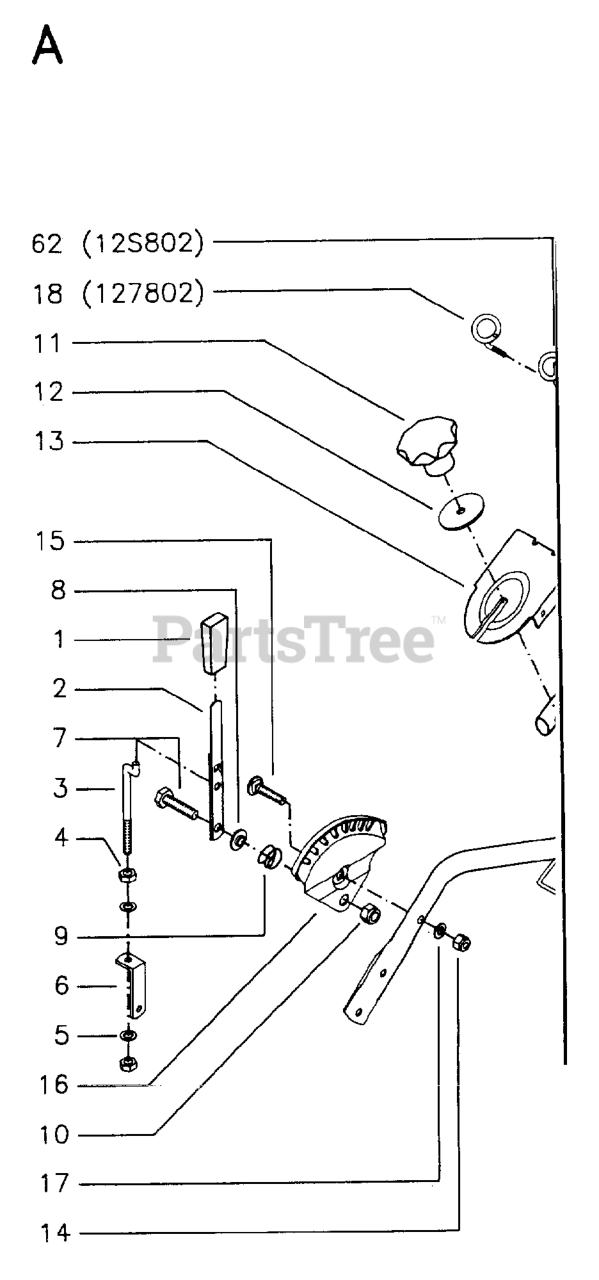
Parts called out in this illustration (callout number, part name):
2	CLUTCH ARM
4	NUT
5	STAR WASHER
9	PRESSURE SPRING
14	LOCKNUT M8
16	INDEXPLATE
17	WASHER - 15X7.3X1.6
18	CABLE GUIDE
62	GUIDE
